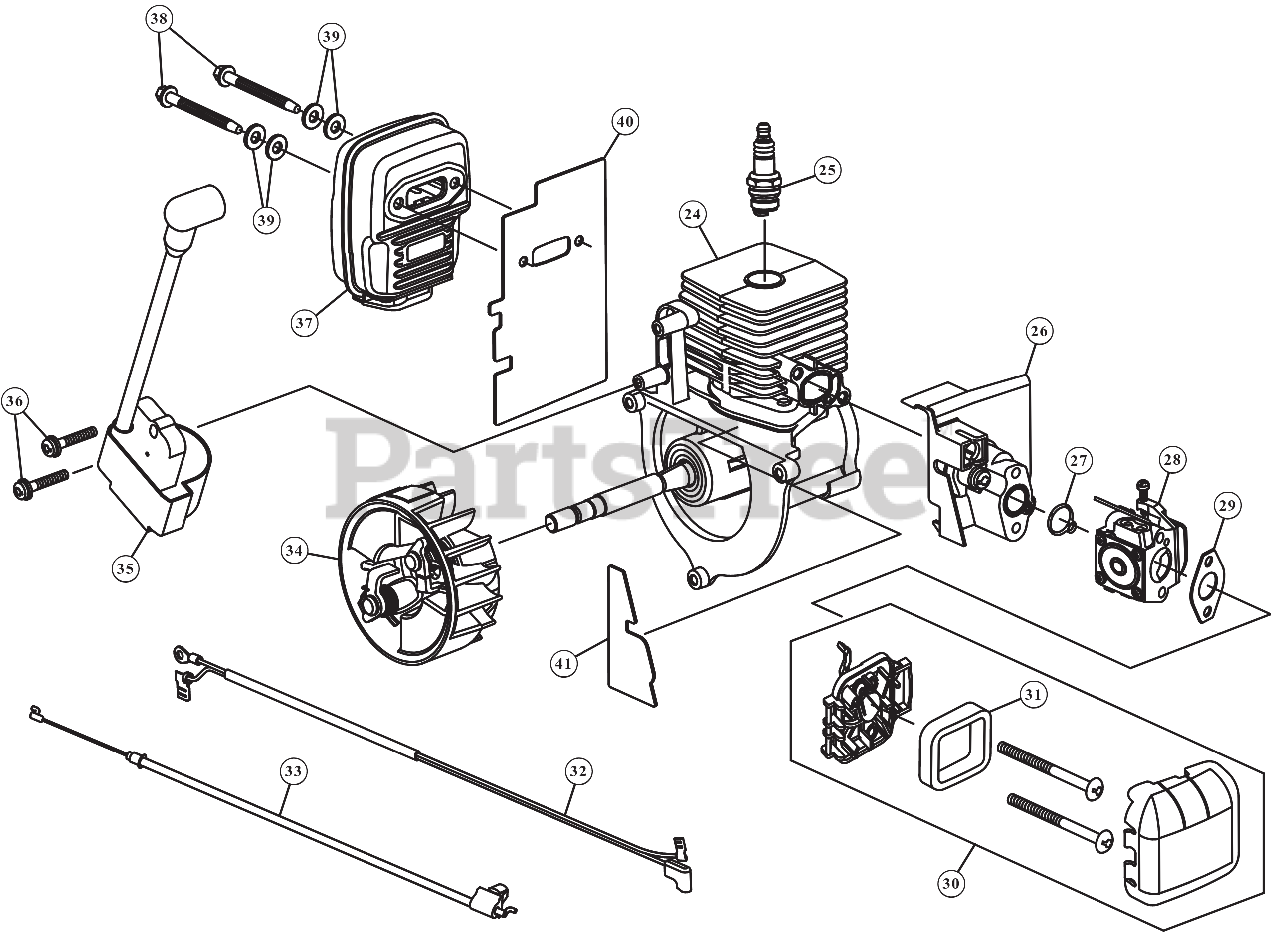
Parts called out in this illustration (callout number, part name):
24	SHORT BLOCK
25	SPARK PLUG
26	INTAKE ASSEMBLY
27	O-RING
28	CARB ASSEMBLY
29	GASKET CARB
30	AIR CLEANER ASSEMBLY
31	AIR FILTER
32	WIRE LEAD
33	THROTTLE CABLE
34	FLYWHEEL ASSEMBLY
35	MODULE
36	SCREW 8-32X.750
37	MUFFLER ASSEMBLY
38	MUFFLER SCREW
39	WASH, FLAT .480X.1
40	GASKET
41	SHORTBLOCK GASKET
